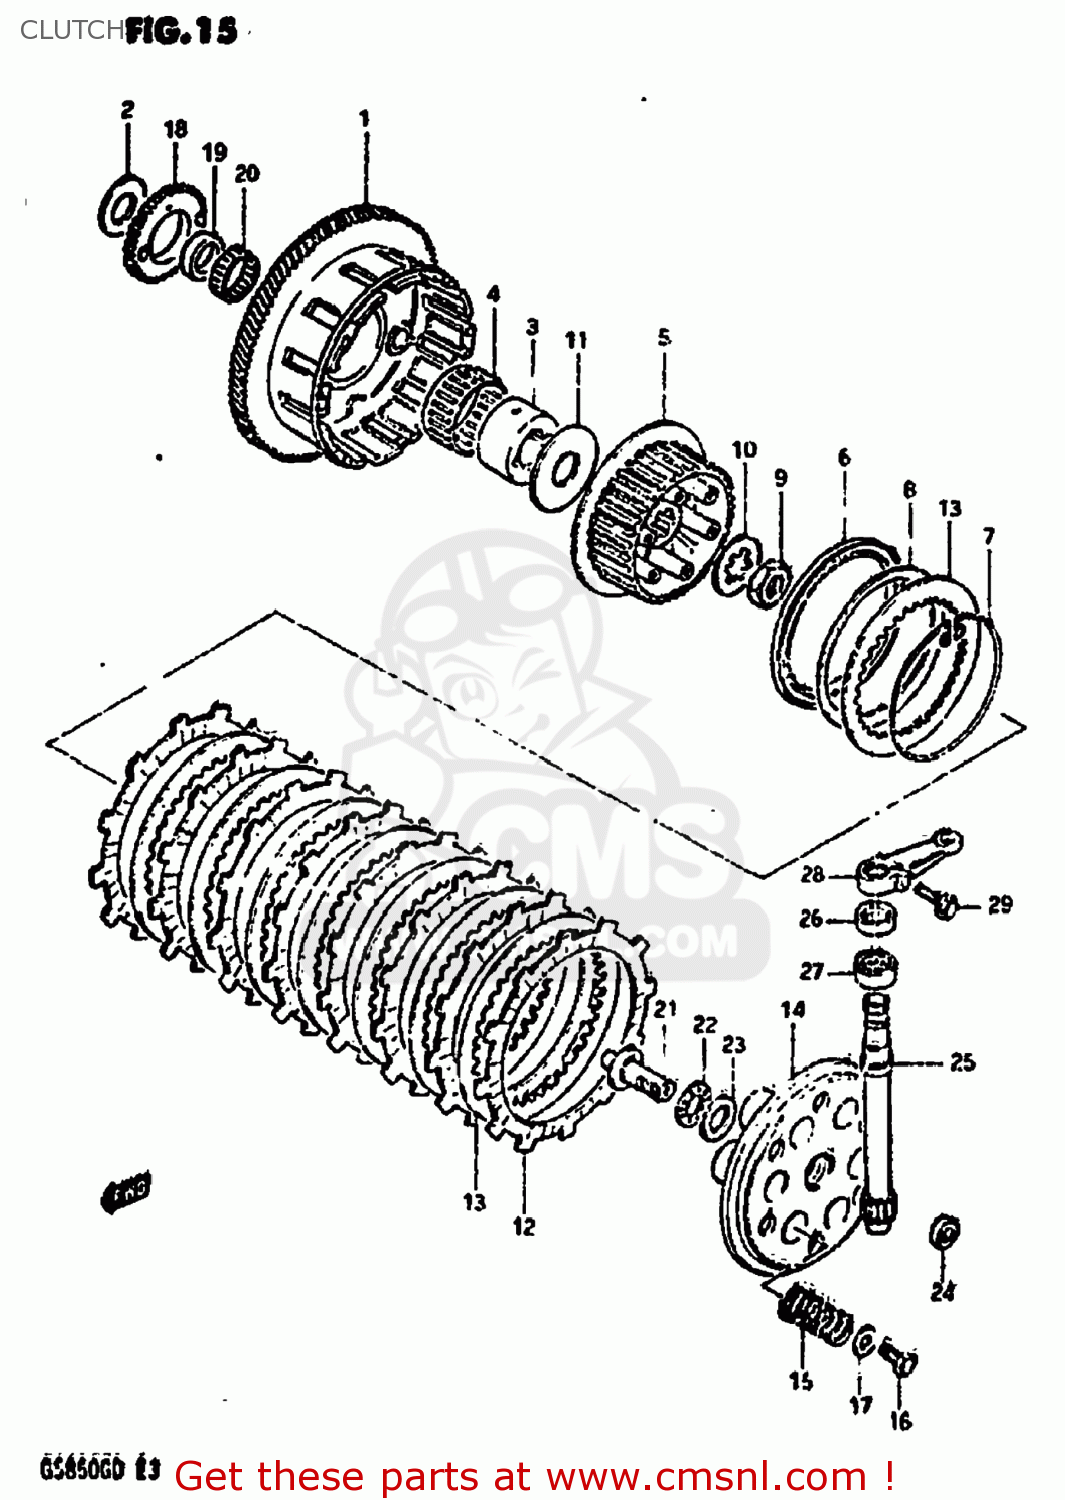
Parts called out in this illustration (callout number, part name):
1	GEAR ASSEMBLY,PRIMARY DRIVE
2	WASHER
3	SPACER
4	BEARING
5	HUB,CLUTCH SLEEVE
6	SEAT,WAVE WASHER
7	RING,STOPPER
8	WASHER
9	NUT
10	WASHER,LOCK
11	WASHER(25X66X3.5)
12	PLATE,CLUTCH DRIVE (MCA)
13	PLATE,CLUTCH DRIVEN(T:2.0) (NAS)
14	DISC,CLUTCH PRESSURE
15	SPRING
16	BOLT, UPPER
17	WASHER
18	GEAR,ENG OIL PUMP DRIVE(NT:34)
19	SPACER,OIL PUMP DRIVE GEAR
20	BEARING(36X40X10)
21	RACK,CLUTCH RELEASE
22	BEARING(15X28X2)
23	WASHER
24	SEAL,OIL(10X16X5)
25	PINION,CLUTCH RELEASE
26	OIL SEAL
27	BEARING(15X22X12)
28	ARM,CLUTCH RELEASE
29	BOLT 6X20
